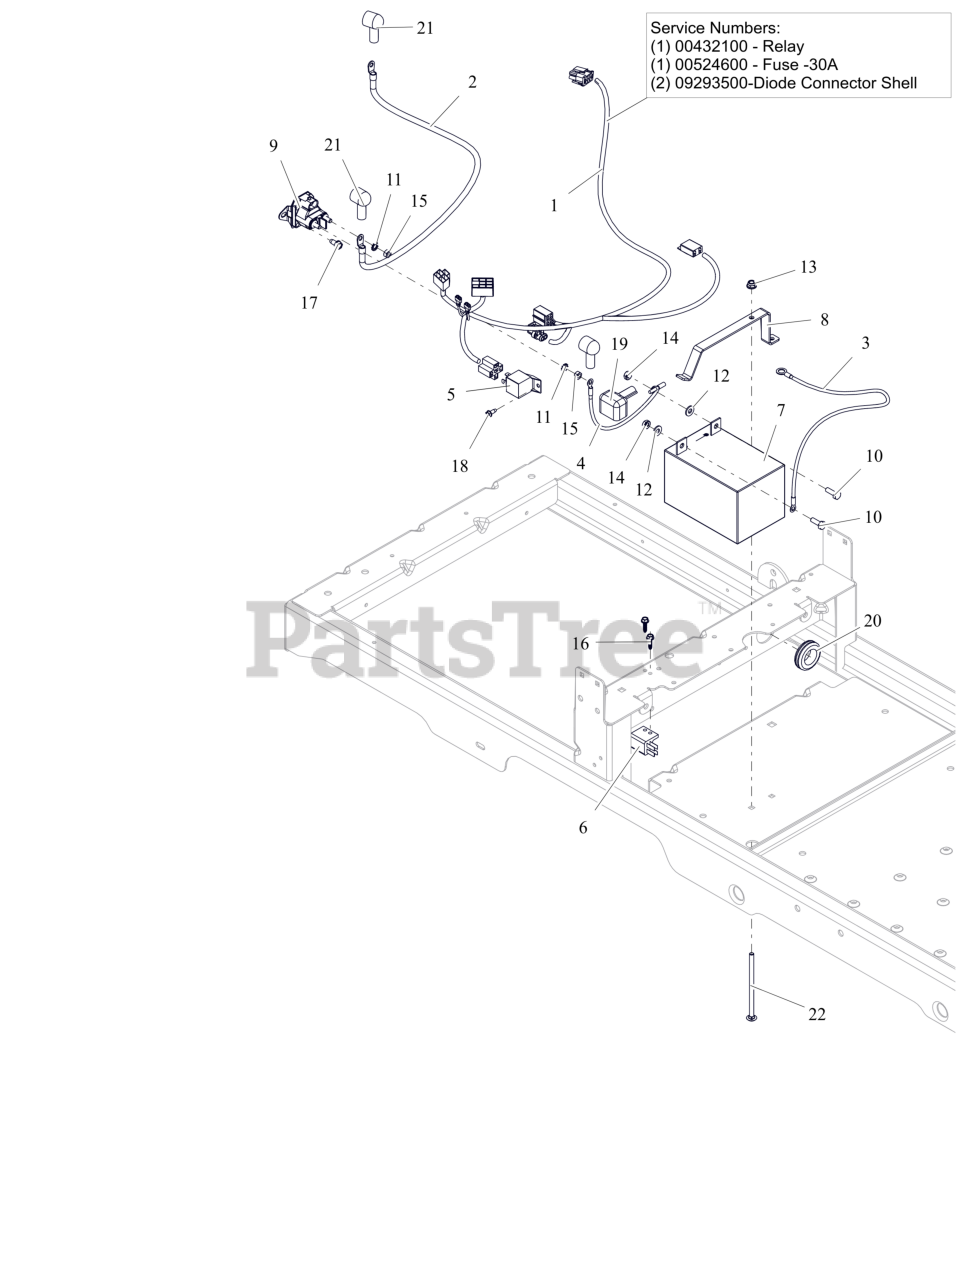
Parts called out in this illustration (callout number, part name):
1	HARNESS, ZOOM / ZT WIRE
1	RELAY,SEALED W/DIODE
1	FUSE, 30 AMP.
1	DIODE, CONNECTOR SHELL
2	CABLE,POS W/(2)1/4 RING 21.5LG
3	CABLE, NEGATIVE 26" 6 GA.
4	CABLE,POS W/2 1/4 RING 15.0 LG
5	RELAY,SEALED W/DIODE
6	SWITCH- DOUBLE POLE N.O./N.O.
7	BATTERY, 12V 12A -190CCA
8	HOLDDOWN, BATTERY, U1&190CCA
9	SOLENOID, STARTER (SEALED)
10	BLT, HEX .25-20X.75 G5 ZCC
11	WSHR,LK-EXT.262X.502X.026 ZCC
12	WSHR,FLT .281X.625X.065 ZCC
13	NUT,NYL-FLG .25-20 GF ZCC
14	NUT-KEPS .250-20 ZCC
15	NUT-STD M6-1.0 ZCC
16	SCR, PLASTITE #12X.75 ZCC
17	SCR-TAP .25-20X.50 HWH ZCC
18	@SCR-TAP 10-24X.50 HWH TR YWZC
19	INSULATOR
20	GROMMET 1.0ID X 1.38 OD
21	BOOT, EYELET TERMINAL
22	BLT, RHSN .25-20X4.50 G5 ZCC
